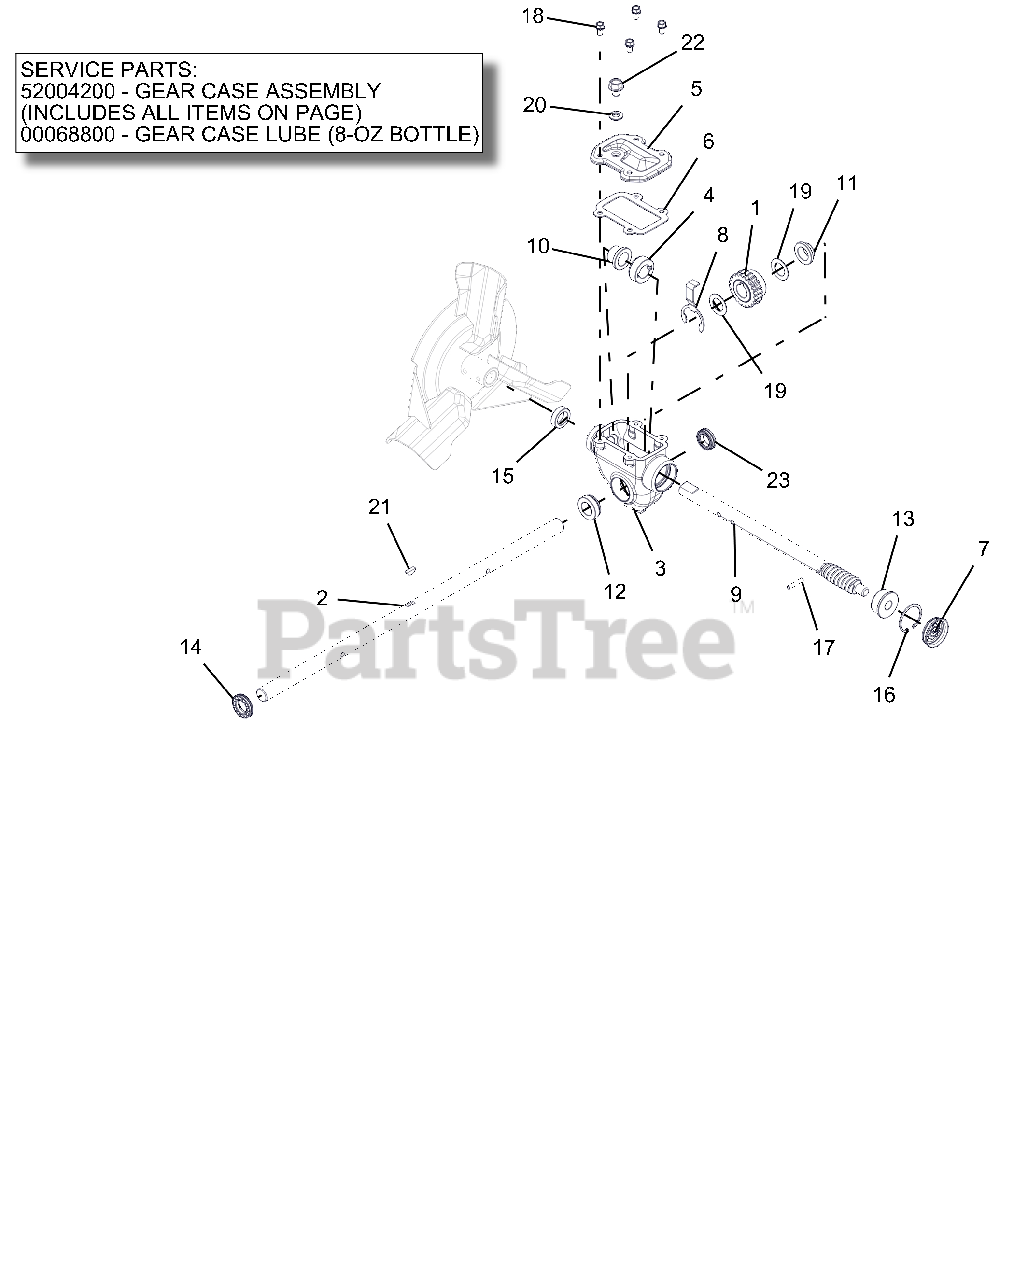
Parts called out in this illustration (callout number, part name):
1	WORM GEAR
2	SHAFT, RAKE - 22" (.750 DIA)
3	GEARCASE, COMPACT MACHINED
4	THRUST COLLAR, .75" ID SLIPFIT
5	COVER, TOP - COMPACT
6	GASKET, TOP - COMPACT GEARCASE
7	COVER, GEAR CASE 1.50"
8	BUSHING RETAINER, COMPACT
9	SHAFT, WORM - COMPACT
10	BSHG-FLG .755X.878X.75X1.25
11	BSHG-FLG .755X.878X.424X1.25
12	BSHG-FLG COMPACT, RIGHT
13	BSHG-FLG .503X1.303X.62X1.465
14	SEAL-OIL .748X1.300X.250 TBC29
15	SEAL-OIL .748X1.125X.312 TB2-H
16	RG-RTNG-INT 1.500X.050
17	PIN-STR .188X1.00 6150
18	BOLT, SEMS .25-20X.50 GR5 YWZC
19	WSHR-FL-STL .760X1.225X.032 YZ
20	WSHR-BND-SEAL .38X.75X.11 GALV
21	KEY-WDRF .19X.63 HRD #61
22	@SCR-ROLOK .38-16X.50 HWH YWZC
23	SEAL-OIL .748X1.125X.312 TBC29
24	GEAR CASE, 22" IRON SM TOP-LD
25	ARIENS L3 LUBE, 8 OZ BOTTLE
